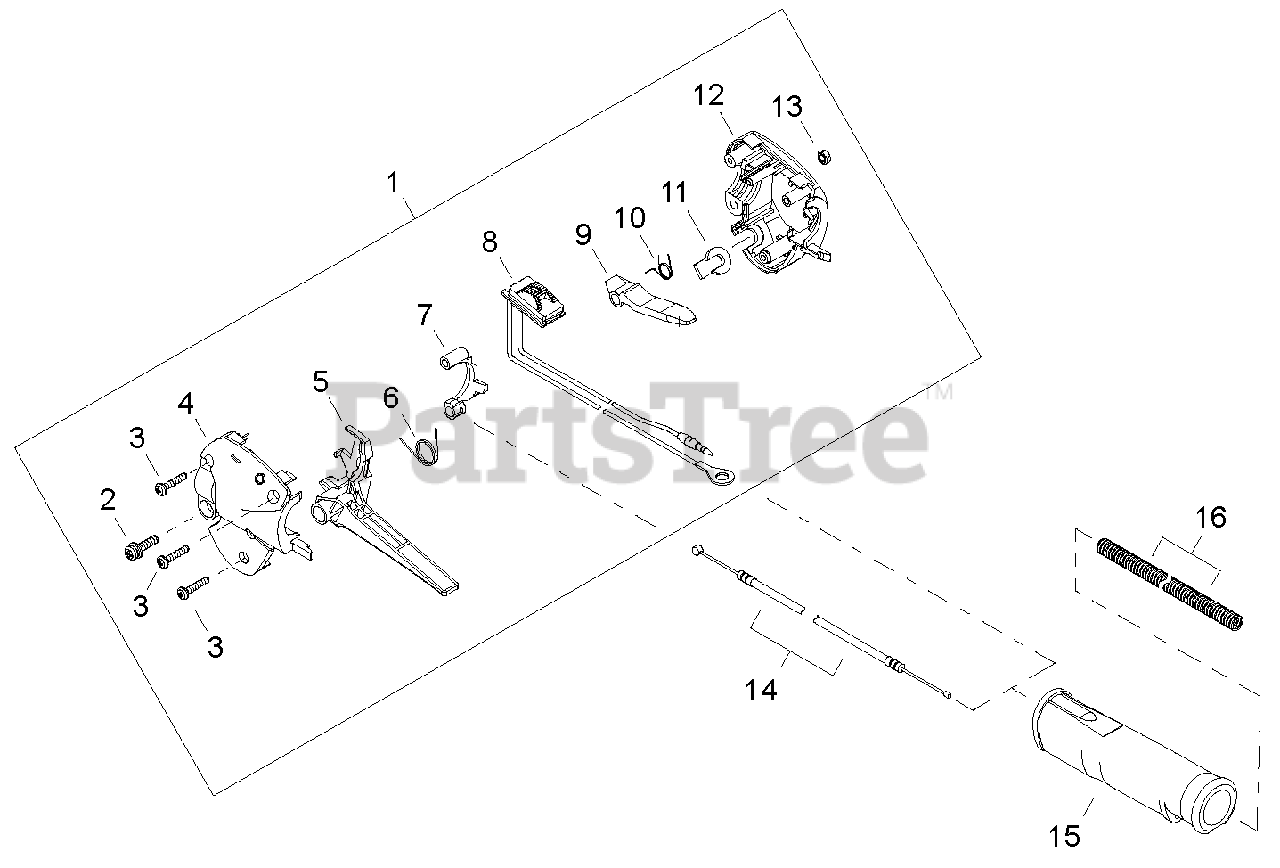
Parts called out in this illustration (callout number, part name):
2	SCREW - 5X20
3	SCREW - 4X20 -- TAPPING
4	HANDLE, CONTROL - LEFT
5	TRIGGER, THROTTLE
6	SPRING
7	LOCKOUT, THROTTLE
8	SWITCH, IGNITION
9	LEVER, TRIGGER LOCKOUT
10	SPRING
11	PLUG
12	HANDLE, CONTROL - RIGHT
12-1	THROTTLE CONTROL ASSY
13	NUT - 5
14	CABLE, THROTTLE
15	GRIP, REAR
16	TUBE, PROTECTIVE - PLASTIC
